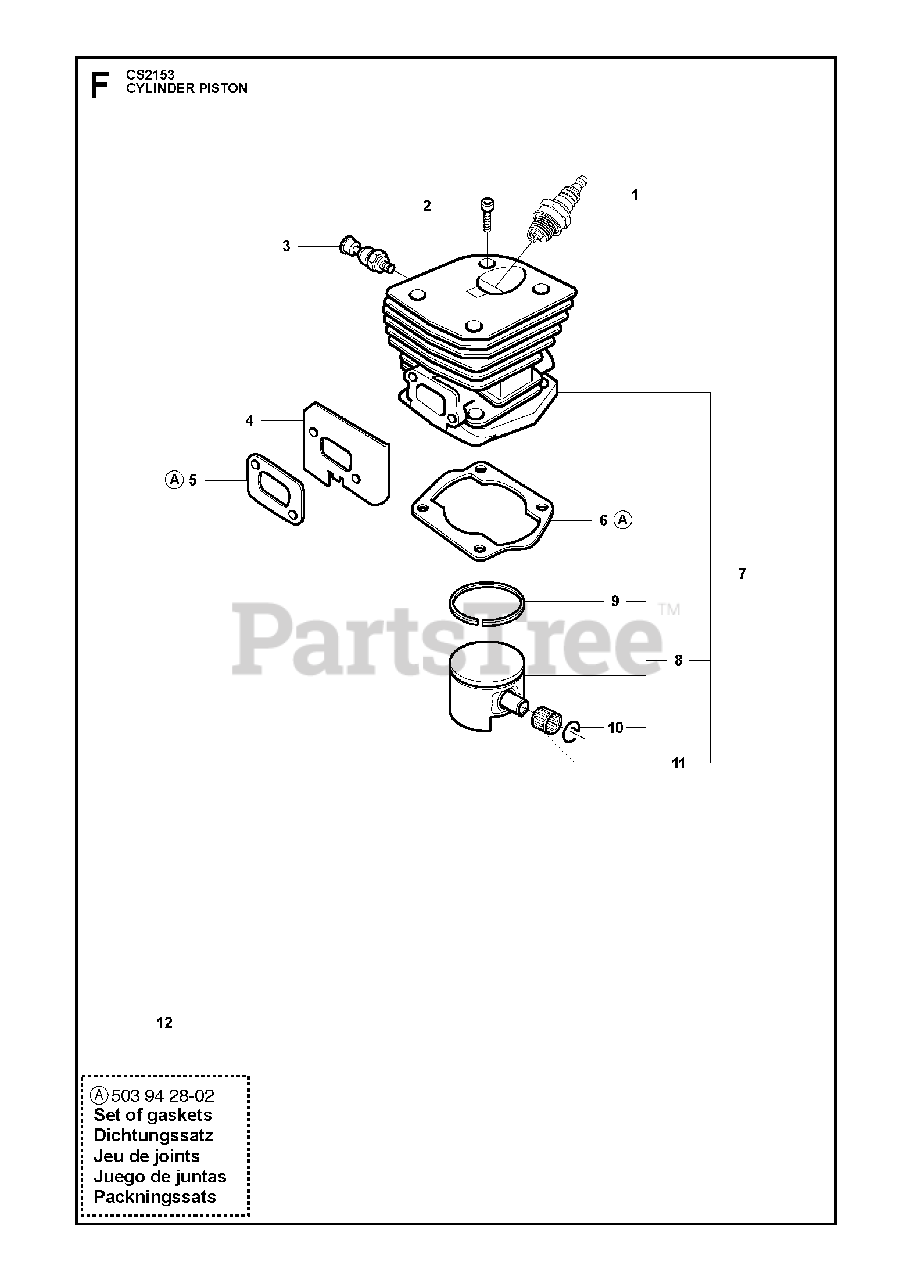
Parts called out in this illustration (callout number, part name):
1	SPARK PLUG RCJ7Y
2	SCREW MC6S 5X25
3	DECOMPRESSION VALVE
5	GASKET
6	GASKET
7	CYLINDER
8	PISTON ASSY
9	PISTON RING
10	LOCKING RING
11	RP SUPPORT BUSHING
12	GASKET SET
